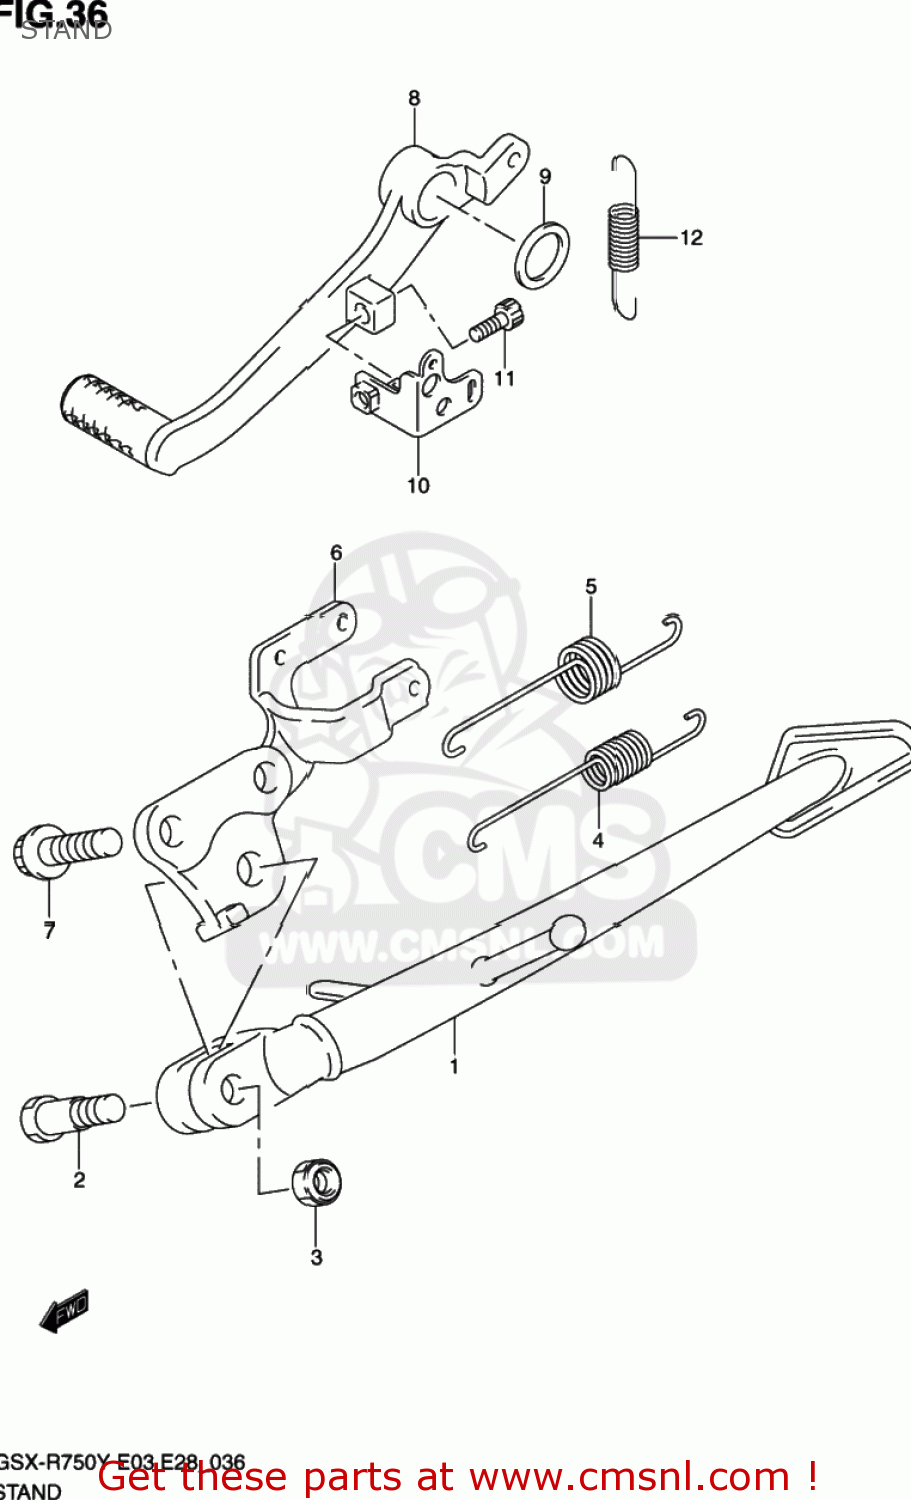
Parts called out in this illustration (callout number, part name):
1	STAND,PROP
2	BOLT(10X37.5)
3	NUT,PROP STAND
4	SPRING
5	SPRING
6	BRACKET COMP,PROP STAND
7	BOLT(10X28)
8	PEDAL,BRAKE
9	WASHER(18X24X1)
10	BRACKET,RETURN SPRING
11	BOLT,OIL FILLE
12	SPRING
